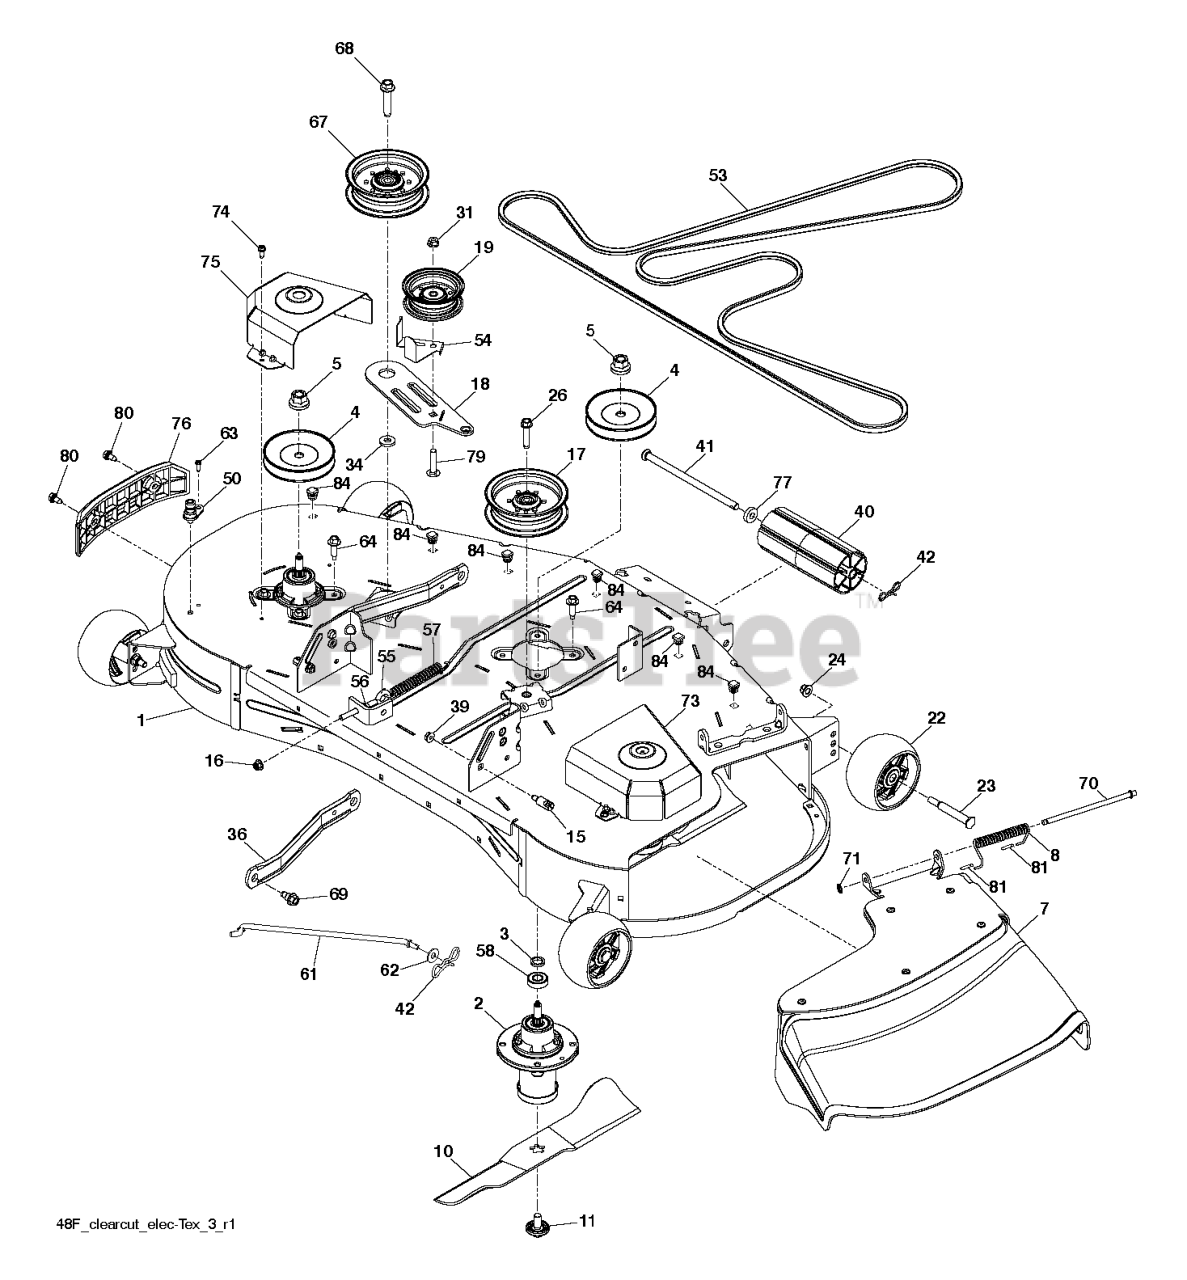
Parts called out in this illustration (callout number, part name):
1	DECK KIT.SVC.48.CC.ASM.668
2	MANDREL ASM, CAST IRON
3	WASHER.SPACER.MANDREL
4	MANDREL PULLEY
5	NUT.FLANGE.LOCK.TOP
7	DEFLECTOR.ASM.48".CLRCT.RES.OR
8	SPRING.42.FCS.DEFLECTOR
10	BLADE.BAGGER.RES.CLRCT.48".BLK
11	BOLT.WASHER.ASM.7/16-2
15	STUD.FASTNER.W/ANTI-ROTATE
16	5/16-18 NYLOC FLANGE NUT
17	PULLEY.IDLER.MWR.STATI.LH
18	ARM.PNT.CLUTCHING.ASM.EDIP
19	PULLEY.IDLER.48"PRIMARY
22	WHEEL.GAUGE.RALLY
23	BOLT.SHOULDER.3/8-16X3-5/8.
24	NUT 3/8-16 HEX FLG NYLOC ZD
26	SCREW.7/16-14 X 2.125.WASHER
31	NUT LOCK FLG 3/8-16 UNC
36	ARM.SUSPENSION.MOWER
39	NUT LOCK HEX FLANGE 5/16-18
40	NOSE ROLLER 48"
41	ROD.ROLLER.NOSE.NARROW.48"
42	PIN.COTTER.5/16.BOW TI
50	PORT.WASHOUT
53	BELT.DECK.TRACTOR
54	GUARD, BELT
55	EYE BOLT 5/16 X 3.50
56	NUT 5/16C WHIZ
57	SPRING.EXTN.42.FCS.TR.DECK.DRV
58	BEARING
61	ROD.ANTI.SWAY.48/54"K4
62	WASHER
63	SCR 1/4-20X5/8 HEX SELF TAP ZD
64	BOLT.HEX.WASHR.HED.313-18X1.19
67	PULLEY.IDLER.2006
68	SCREW LT
69	BOLT.SHOULDER
70	ROD.HINGE
71	NUT PUSH M
73	COVER.PNT.MANDREL.RH.GREY
74	SCREW.1/4-20X5/8
75	COVER.PNT.MANDREL.LH.TR.GREY
76	BUMPER.ASM.SIDE.TRIM.CLRCUT.48
77	BUSHING.NOSE.ROLLER
80	SHOULDER BOLT 5/16-18TT
81	CAP-SLEEVE LT
